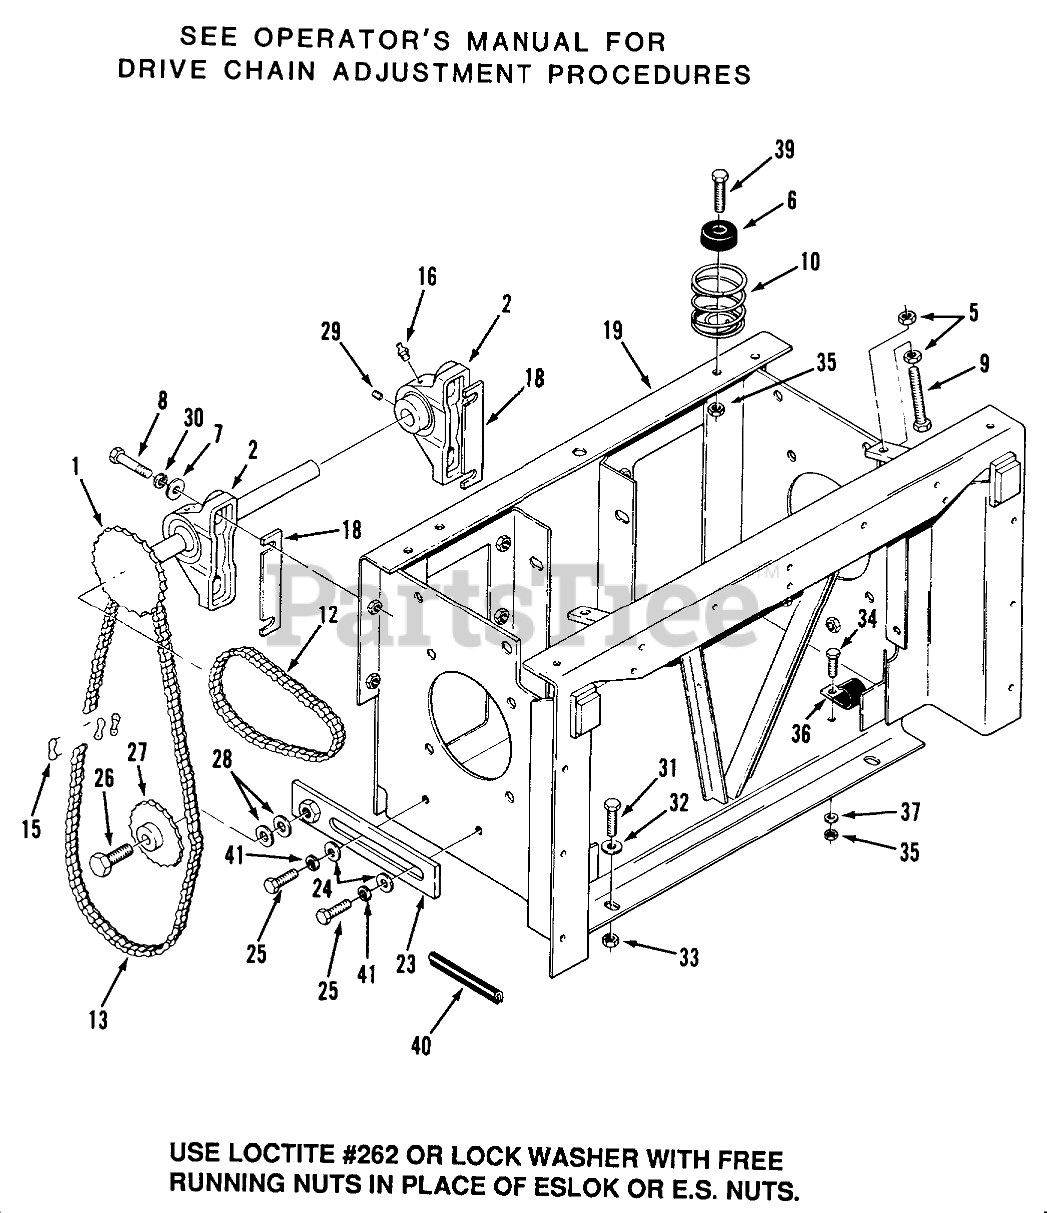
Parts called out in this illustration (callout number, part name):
1	ASSY-JACKSHAFT PLT
2	Pillow Block Bearing (includes items 16 & 29)
5	Nut
6	BUMPER
7	Bolt
8	BOLT
9	Hex Hd. Mach. Screw 5/16-18 x 2-1/4
10	SPRING
12	CHAIN-#50 PRIMARY
13	ROLLER-CHAIN #50 SEC
15	CONNECTING LINK
16	Fitting-Grease
18	SHIM-PILLOW BLOCK
19	Transaxle Frame
23	ASSY-CHAIN TENSIO B
24	Washer
25	BOLT
26	HEX HD CAP SCREW
27	IDLER SPROCKET 20288
28	WASHER
29	SCREW-SET
30	LOCKWASHER
31	BOLT
32	Washer
33	NUT
34	Bolt
35	Nut
36	CLIP
37	WASHER 5/16 SAE
39	Bolt
40	EDGE TRIM
41	LOCKWASHER
43	NUT
44	Seat Switch
